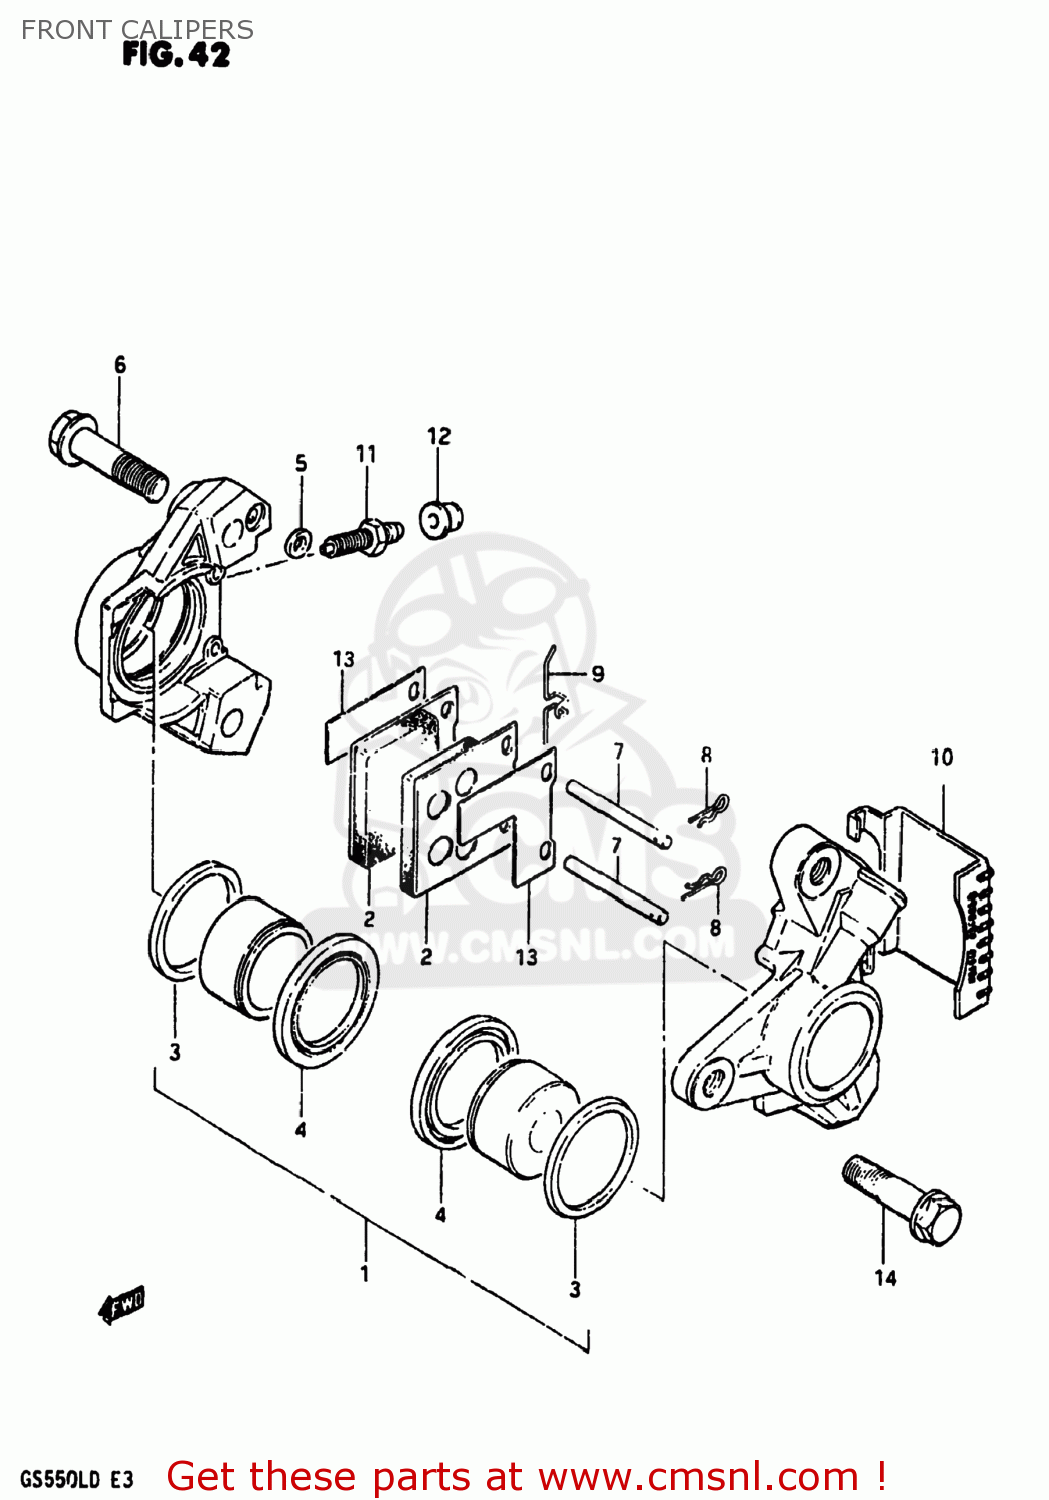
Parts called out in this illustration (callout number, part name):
1	PISTON SET
2	PAD (MCA)
3	SEAL,PISTON
4	BOOT
5	SEAL,JOINT
6	BOLT
7	PIN,PAD
8	CLIP,PAD PIN
9	SPRING
10	COVER,CALIPER
11	BLEEDER
12	CAP,BREATHER
13	SHIM
14	BOLT
